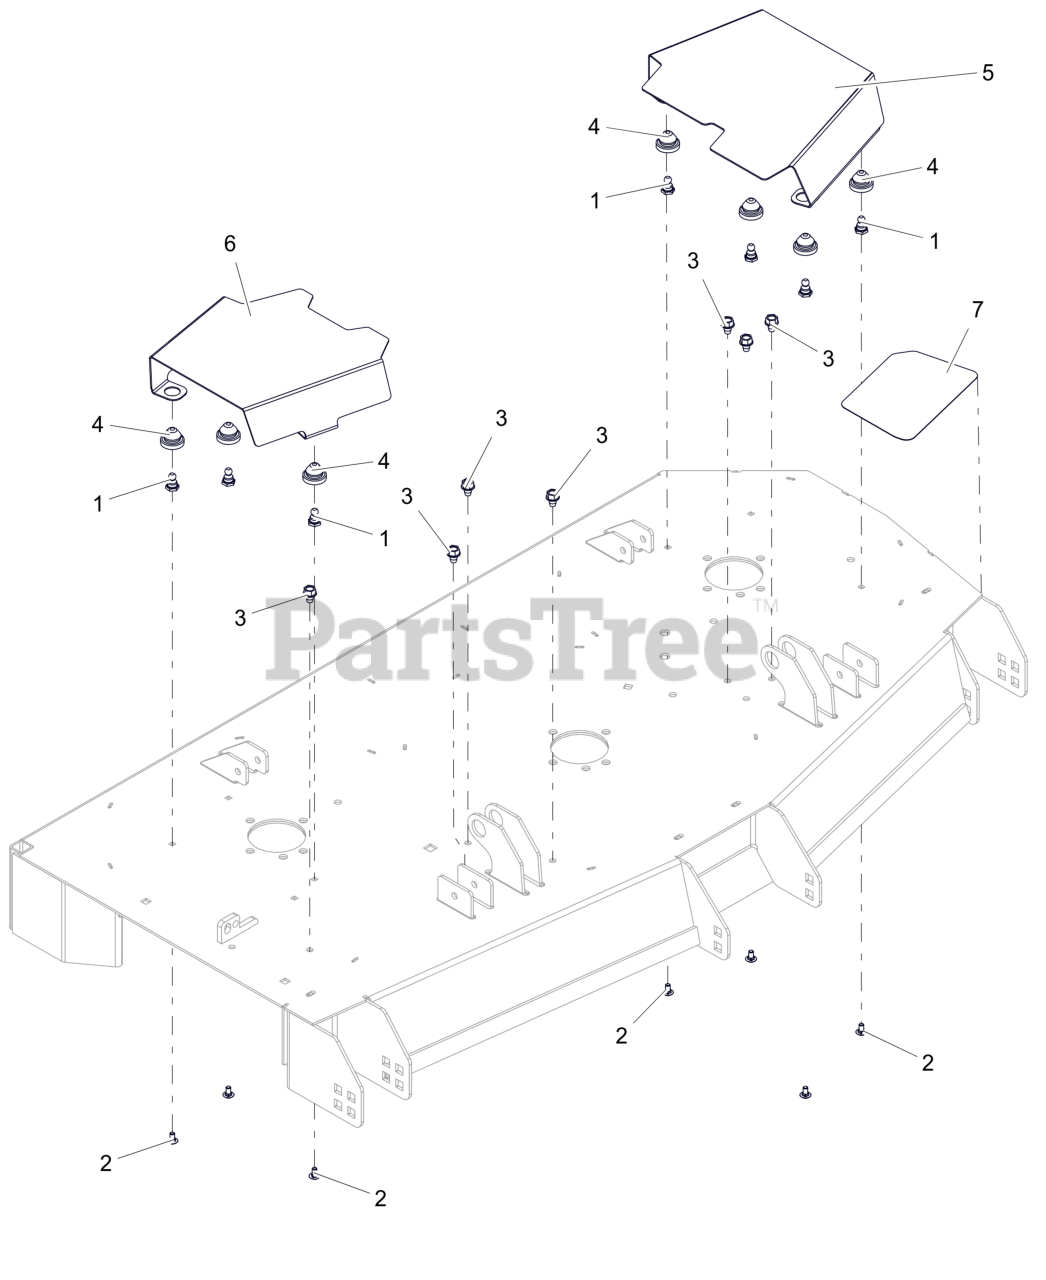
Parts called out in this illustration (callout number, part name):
1	STUD, BALL FEMALE .250-20 THREAD
2	BLT, RHSSN.25-20X.500 G5 ZCC
3	SCR,TAP .375-16X.50 HWH TR ZCC
4	COUPLING, RUBBER PUSH-IN
5	COVER- BELT 52" LEFT
6	COVER- BELT 52" RIGHT
7	GRIP, STEP ANTI SKID HD XF3
